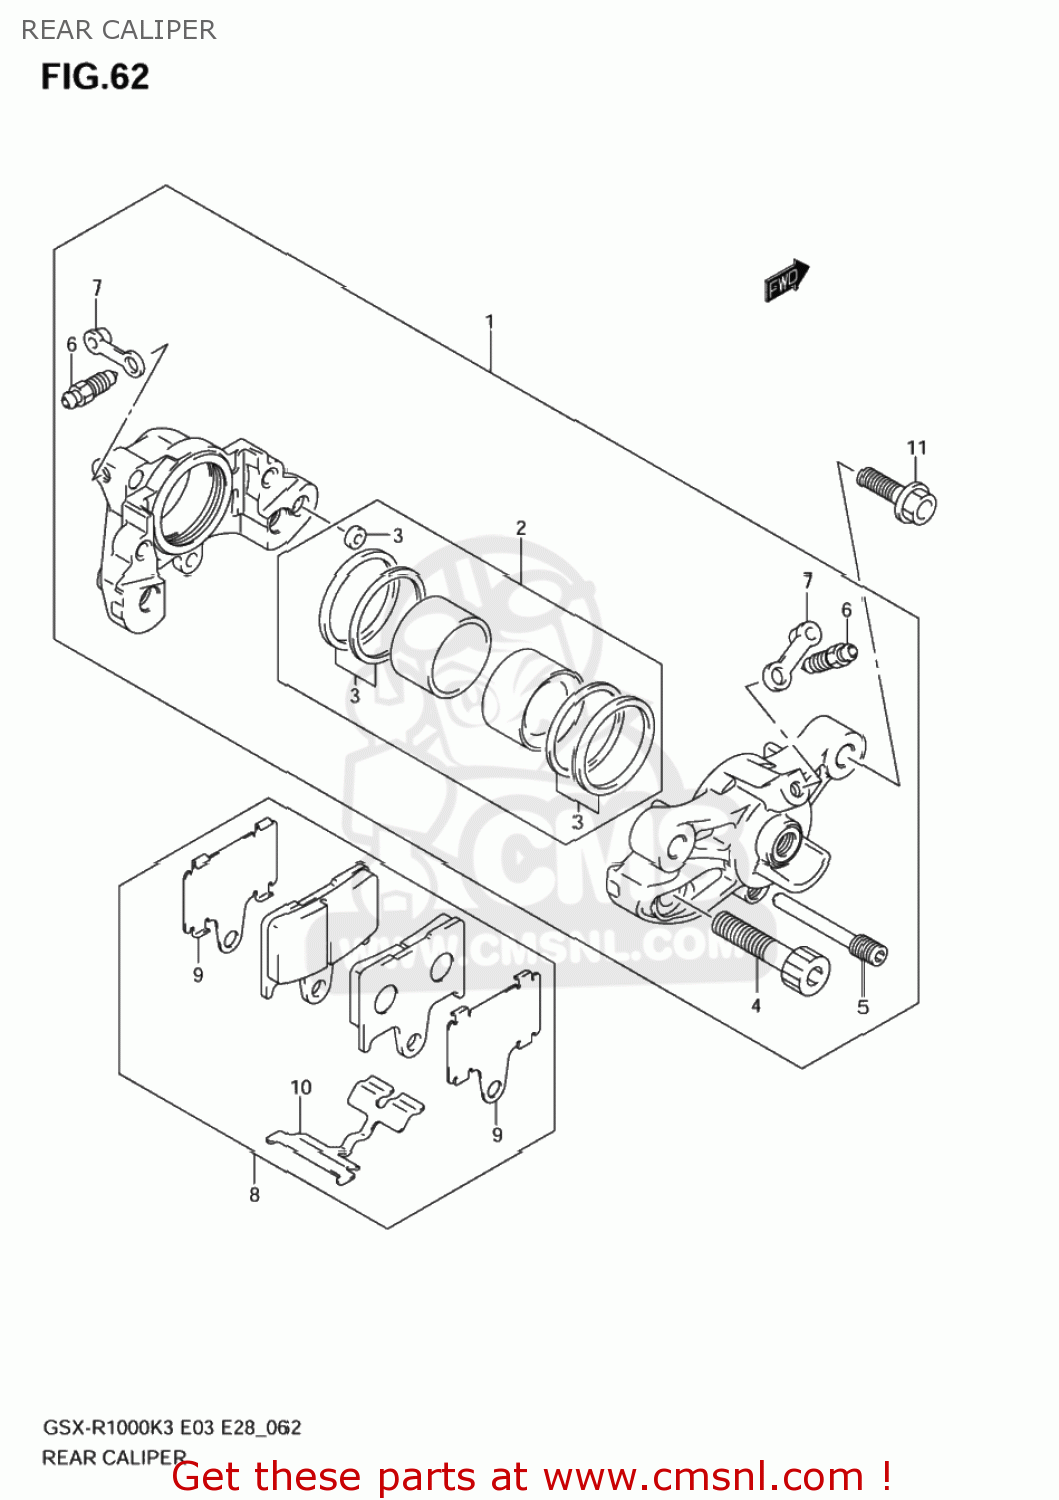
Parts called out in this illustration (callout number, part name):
1	CALIPER ASSY,RR
2	PISTON SET
3	SEAL SET,PISTON
4	BOLT,HOUSING
5	PIN,PAD
6	BLEEDER
7	CAP,BLEEDER
8	PAD & SPRING SET (NAS)
9	SHIM,PAD
10	SPRING,PAD
11	BOLT(8X28)
